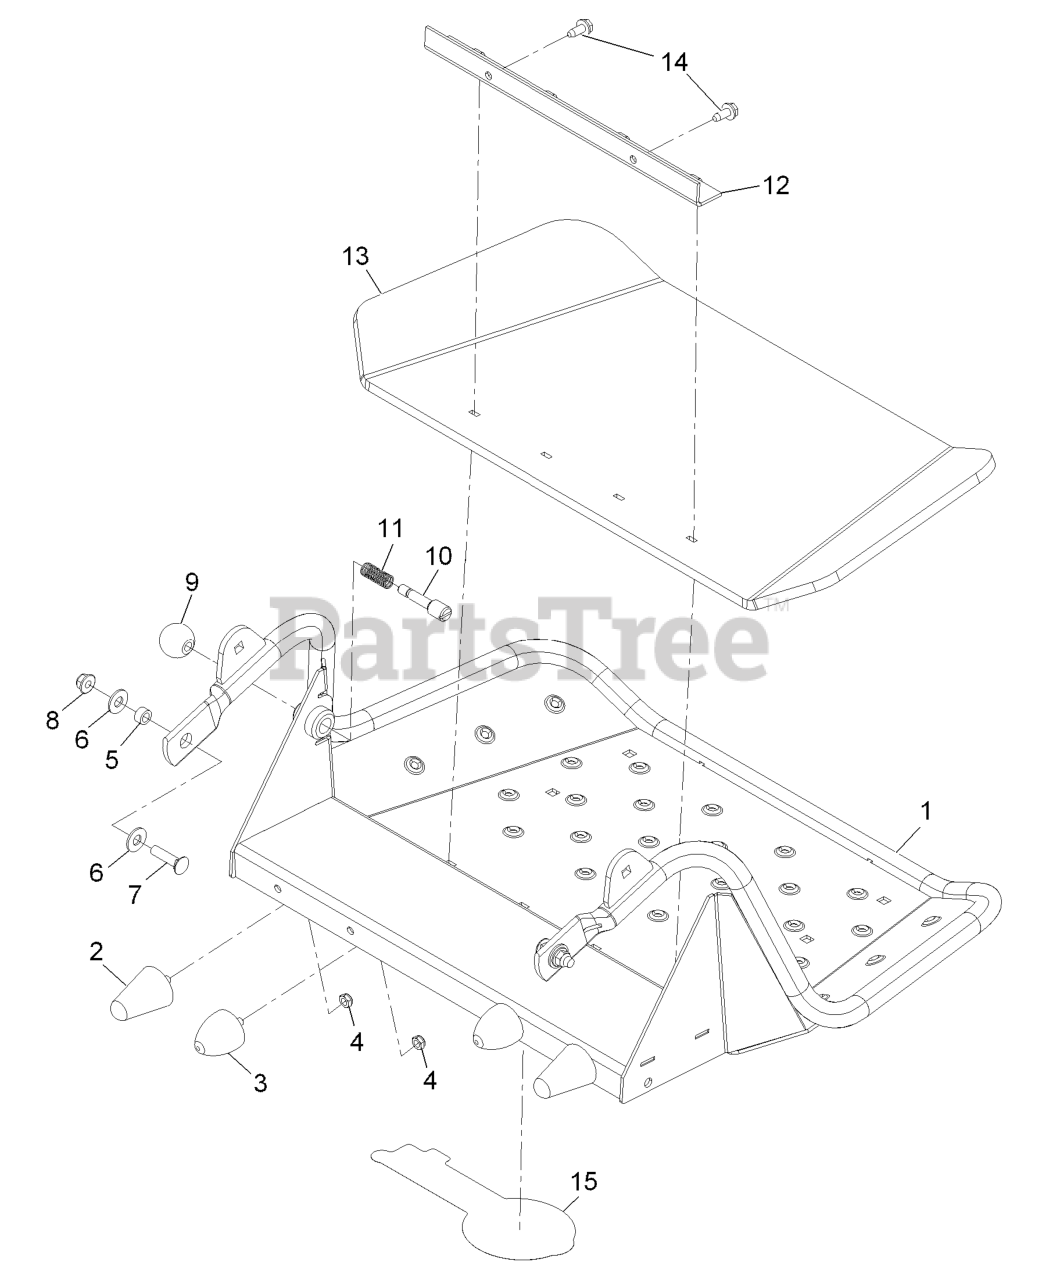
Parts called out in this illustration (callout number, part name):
1	PLATFORM ASM
2	BUMPER-RUBBER
3	BUMPER-RUBBER
4	NUT-LOCK, NI
5	SPACER
6	WASHER-FLAT
7	SCREW-CARR
8	NUT-HF, NI
9	KNOB-BALL
10	PIN-LATCH
12	CLAMP-SHIELD
14	Screw-HWH 5/16-18 X 3/4 Tf
15	DECAL, EXMARK LOGO
